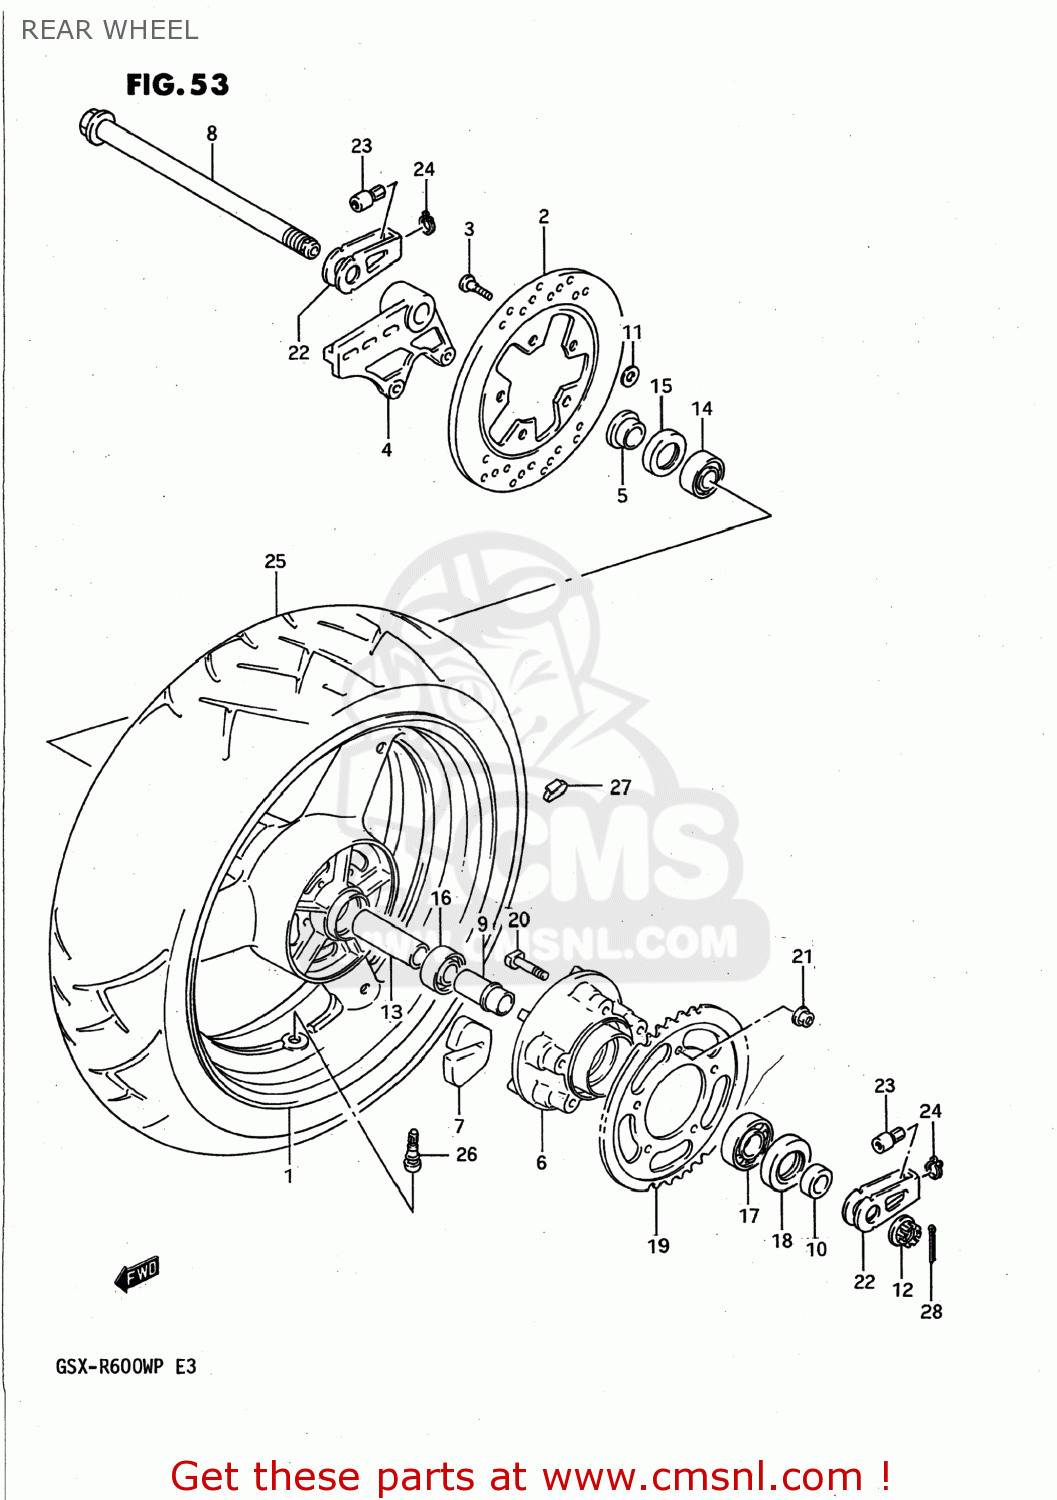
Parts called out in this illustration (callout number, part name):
1	WHEEL,REAR (17XMT5.50)
2	DISC,RR BRAKE
3	BOLT 8X33
4	BRACKET,REAR CALIPER
5	SPACER,RR AXLE,R
6	DRUM,RR SPROCKET MOUNTING
7	ABSORBER,RR HUB SHOCK
8	AXLE,RR
9	RETAINER,RR HUB BEARING
10	SPACER,RR AXLE,L
11	SHIM(10X20X0.3) (NAS)
12	NUT
13	SPACER (20,8X27.2X102)
14	BEARING
15	SEAL,OIL(28X47X7)
16	BEARING(20X47X14)
17	BEARING(25X62X17)
18	SEAL,OIL(35X62X8)
19	SPROCKET,RR(44T)
20	BOLT
21	NUT
22	ADJUSTER,CHAIN
23	ADJUSTER,CHAIN
24	CIRCLIP
25	TIRE,REAR 170/60 ZR17
26	VALVE ASSY,WHEEL RIM(TR412)
27	BALANCER,WHEEL
28	PIN, COTTER
